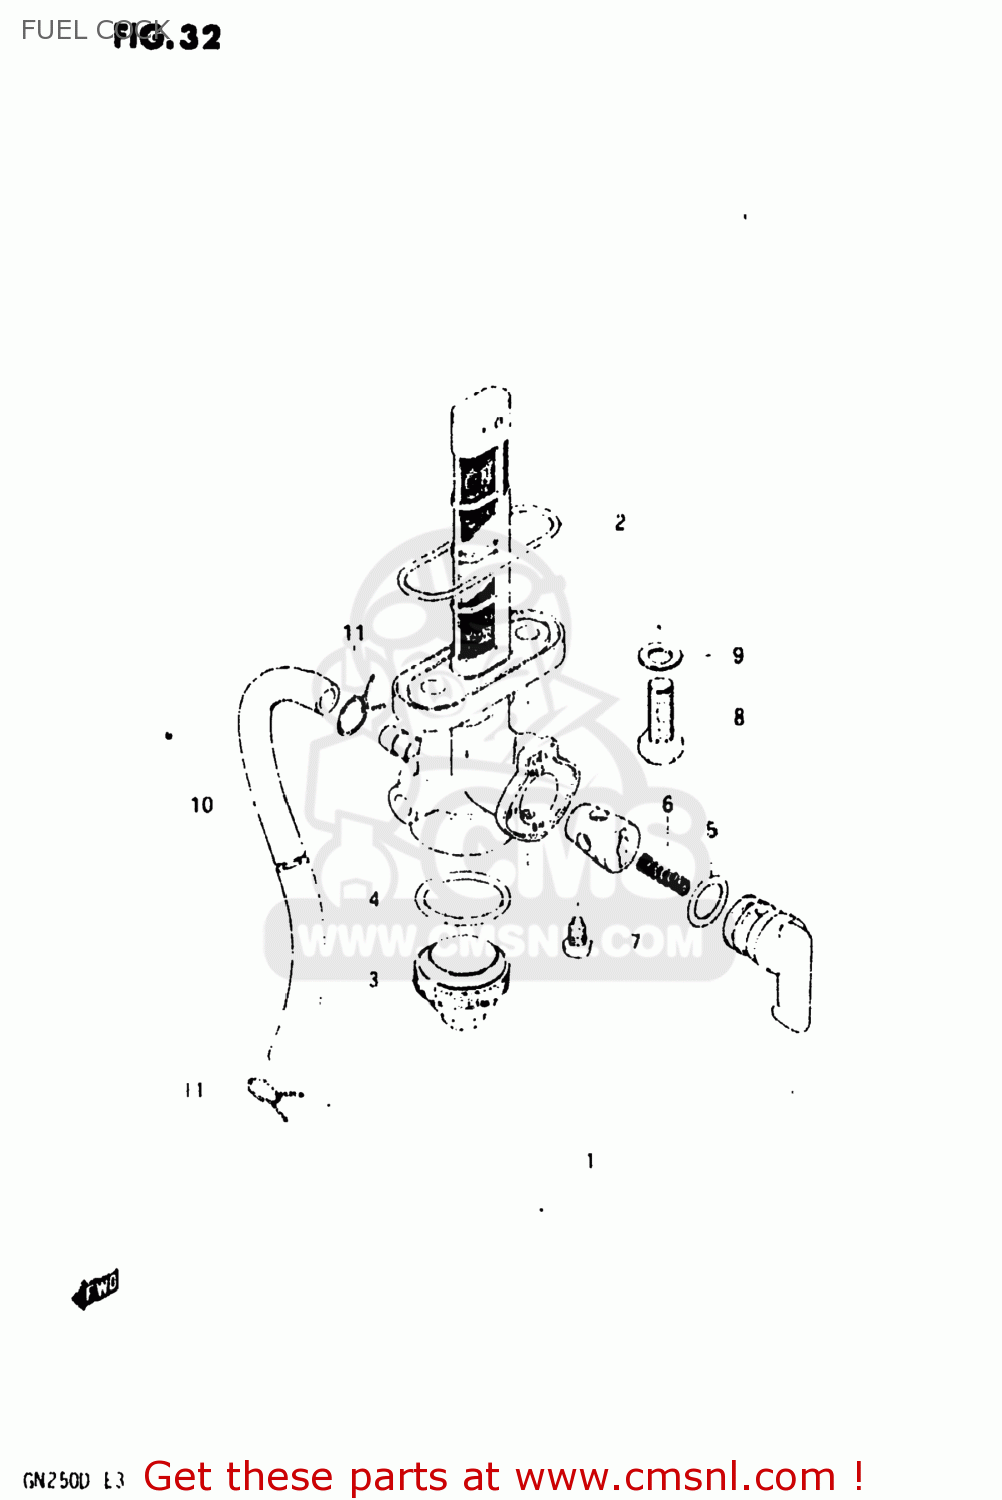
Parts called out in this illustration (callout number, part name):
1	COCK ASSEMBLY,FUEL
2	O RING,FUEL COCK
3	CUP,STRAINER
4	GASKET,FILTER (NAS)
5	O-RING
6	SPRING
7	SCREW
8	BOLT(6X20)
9	GASKET
10	HOSE
11	CLIP
